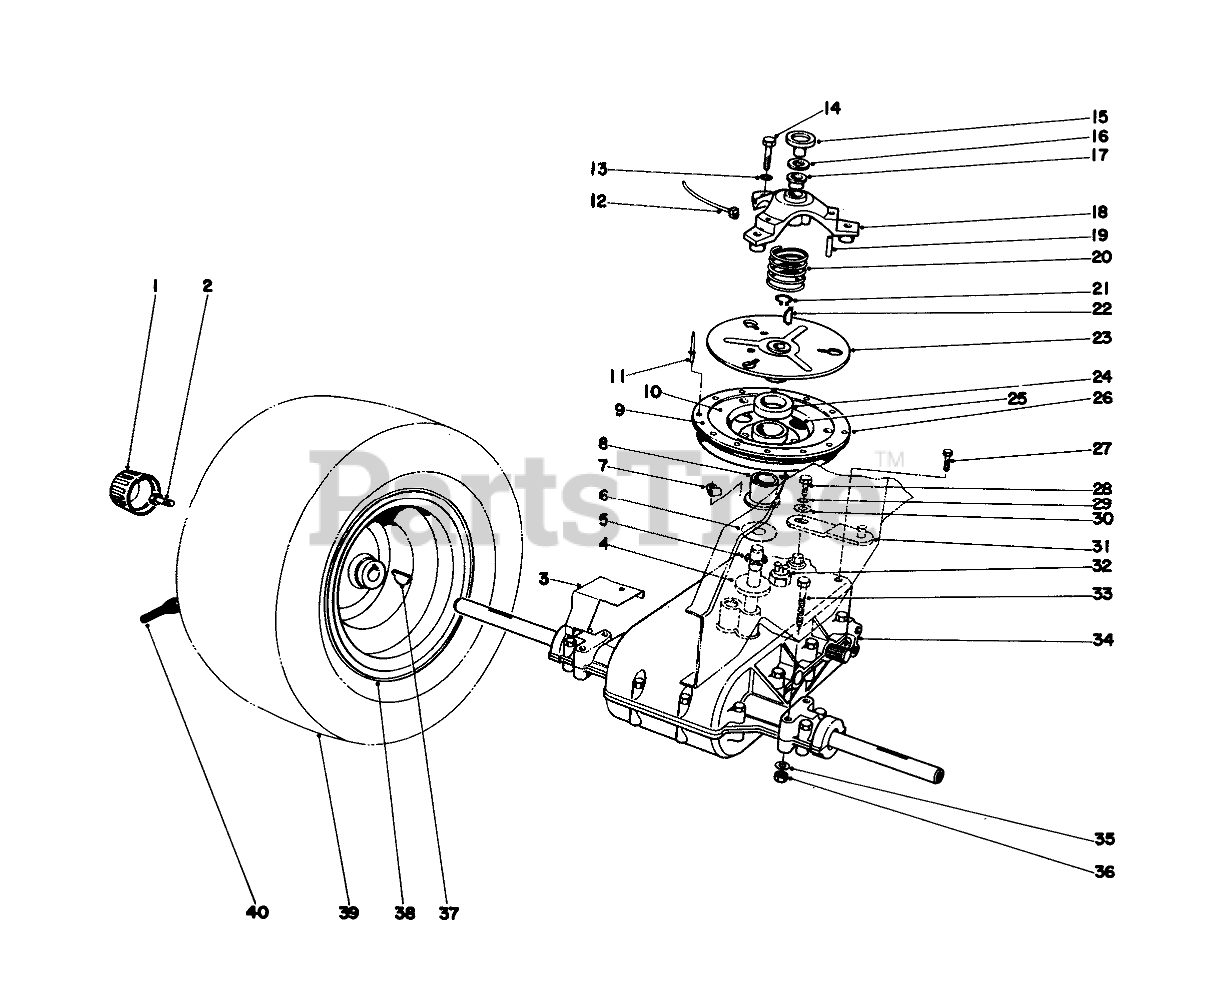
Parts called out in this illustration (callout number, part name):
1	Cap-Hub
2	Capscrew
3	GRASS SHIELD B
4	THRUST WASHER
5	NEEDLE BRG
6	THRUST WASHER
7	CLIP-FUEL LINE
8	Bushing
9	CLUTCH PAD
10	Retainer Ring
11	Rivet
12	Push Mount Tie
13	WASHER-LOCK
14	SCREW-HH
15	CLUTCH CAP
16	THRUST RACE
17	BUSHING-FLANGE
18	Clutch Cover (Incl. Ref. #17 & 19)
19	NEEDLE BRG
20	COMPRESSION SPRING
21	RING-SNAP, EXTERNAL
22	KEY-WOODRUFF
23	Clutch Plate
24	Felt Washer
26	Sheave Assembly (Incl. Ref. #8-11)
27	SCREW-HWHTF
28	SCREW-HH
29	WASHER-LOCK
30	WASHER-FLAT
31	SHIFT LEVER WA B
32	Switch-Neutral
33	SCREW-HH
34	Transaxle
35	WASHER-PLAIN
36	NUT-LOCK, CONE
38	Rim
39	16 X 7.5-8 REAR TIRE
40	STEM-VALVE
